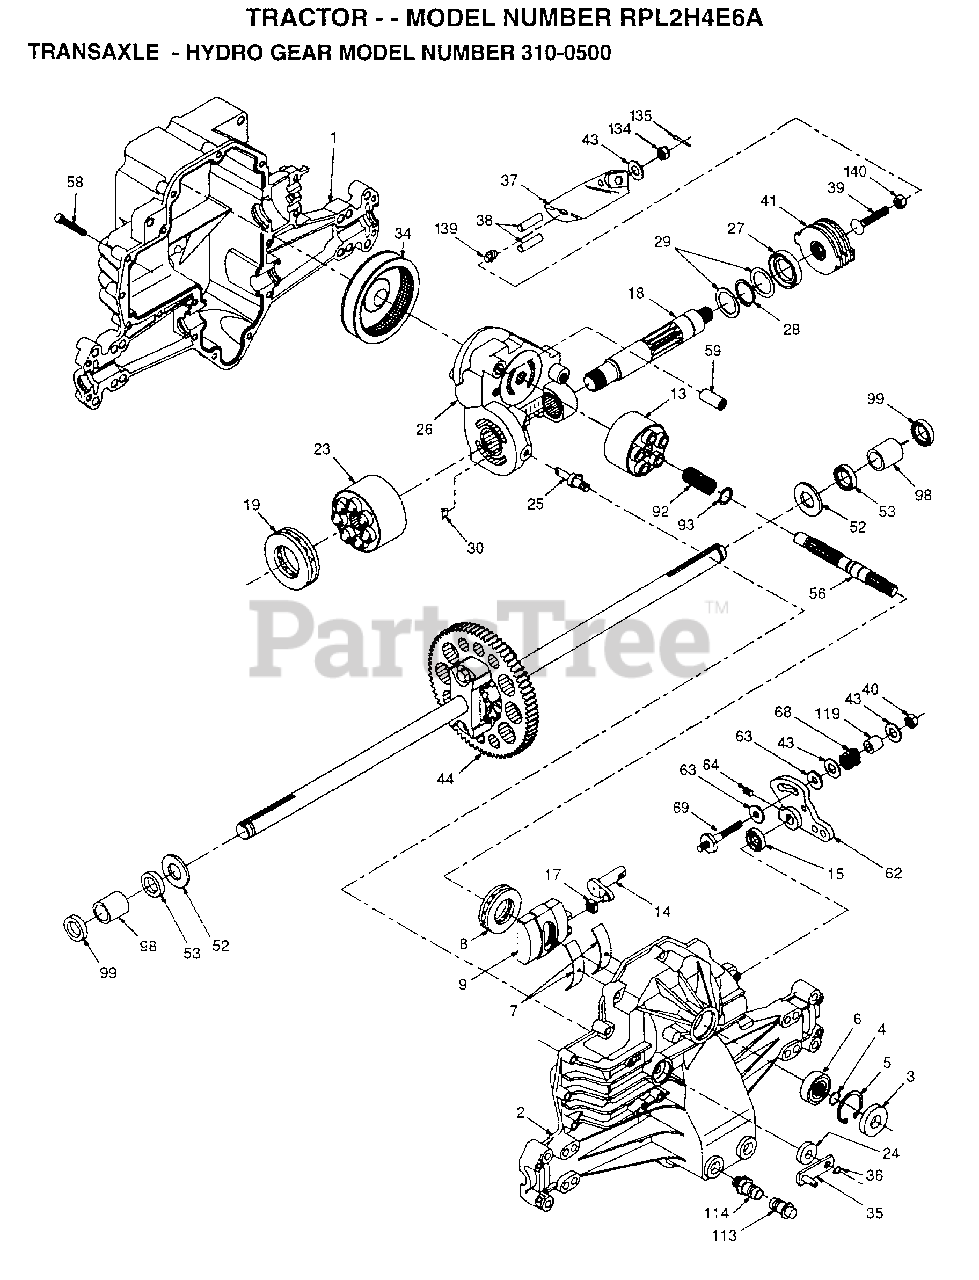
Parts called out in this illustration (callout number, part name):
1	HOUSING.L.44863RM
2	HOUSING.UPR.70122
3	SEAL.9008000-0128
4	RING.RET.2003016.
5	RING.RET.2003052.
6	BEARING.(50552)42X68X16
7	CRADLE- 2003023.
8	BEARING.THU.50551
9	SWASHPLT.2003087.
13	BLOCK.CLYN.70079.
14	ARM.TRUN.2003005.
15	SEAL.9008000-0126
17	GUIDE.2000015.
18	SHAFT.MOTOR.50449
19	BEARING.THU.50552
23	BLOCK.CYLIN.70082
24	SEAL.LIP.45074
25	ACTUATOR.2003555
26	KIT.CEN.SEC.70250
27	SEAL.LIP.45075
28	RING RETAIN 50007
29	WASHER.44872
30	PLATE.BYP.2003554
34	ELEMENT.OIL.44964
35	ARM.BYPASS.50270
36	RING.RETAIN.44870
37	ARM.ACTUAT.23710
38	PIN.ACTUAT.44891
39	BOLT.50316
40	NUT.LOCK.HX.50317
41	KIT.BRAKE.70135
43	WASHER HYD 44130
44	DIFFERNTIAL.70126
52	WASHER.HYD.44875
53	SEAL.HYDRO.45076
56	SHAFT.INPUT.50005
58	BOLT.1/4-20.44876
59	PIN.HYDRO.50002
62	ARM.CONTROL.50254
63	PUCK.DAMPER.50281
64	SCREW.SET.50018.
68	SPRING.HYD.50277
69	STUD.5/16-24.DANA
92	SPRING.2003014.
93	WASHER.2003017
98	BEARING.SLV.50137
99	SEAL.WIPER.50941
113	CAP.VENT.70109
114	O-RING.ASM.70110
119	SPACER.HYD.50278
134	NUT.CAS.HYD.44142
135	PIN.COT.HYD.44101
139	SPRING.COMP.50431
140	NUT.HEX.50269
